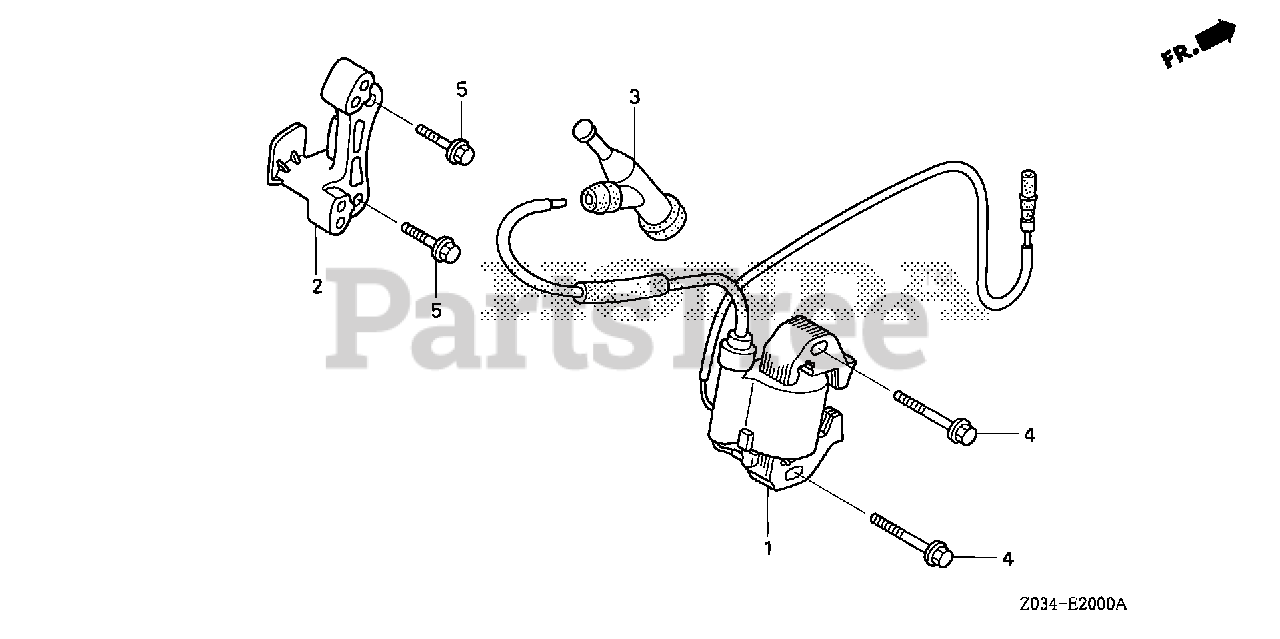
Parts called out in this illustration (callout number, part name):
1	COIL ASSY., IGNITION
2	BRACKET, IGNITION COIL
3	CAP ASSY., NOISE SUPPRESSOR (NICHIWA Y-EZ RTFM256)
4	BOLT, FLANGE (6X32) (CT200)
5	BOLT, FLANGE (6X20) (CT200)
